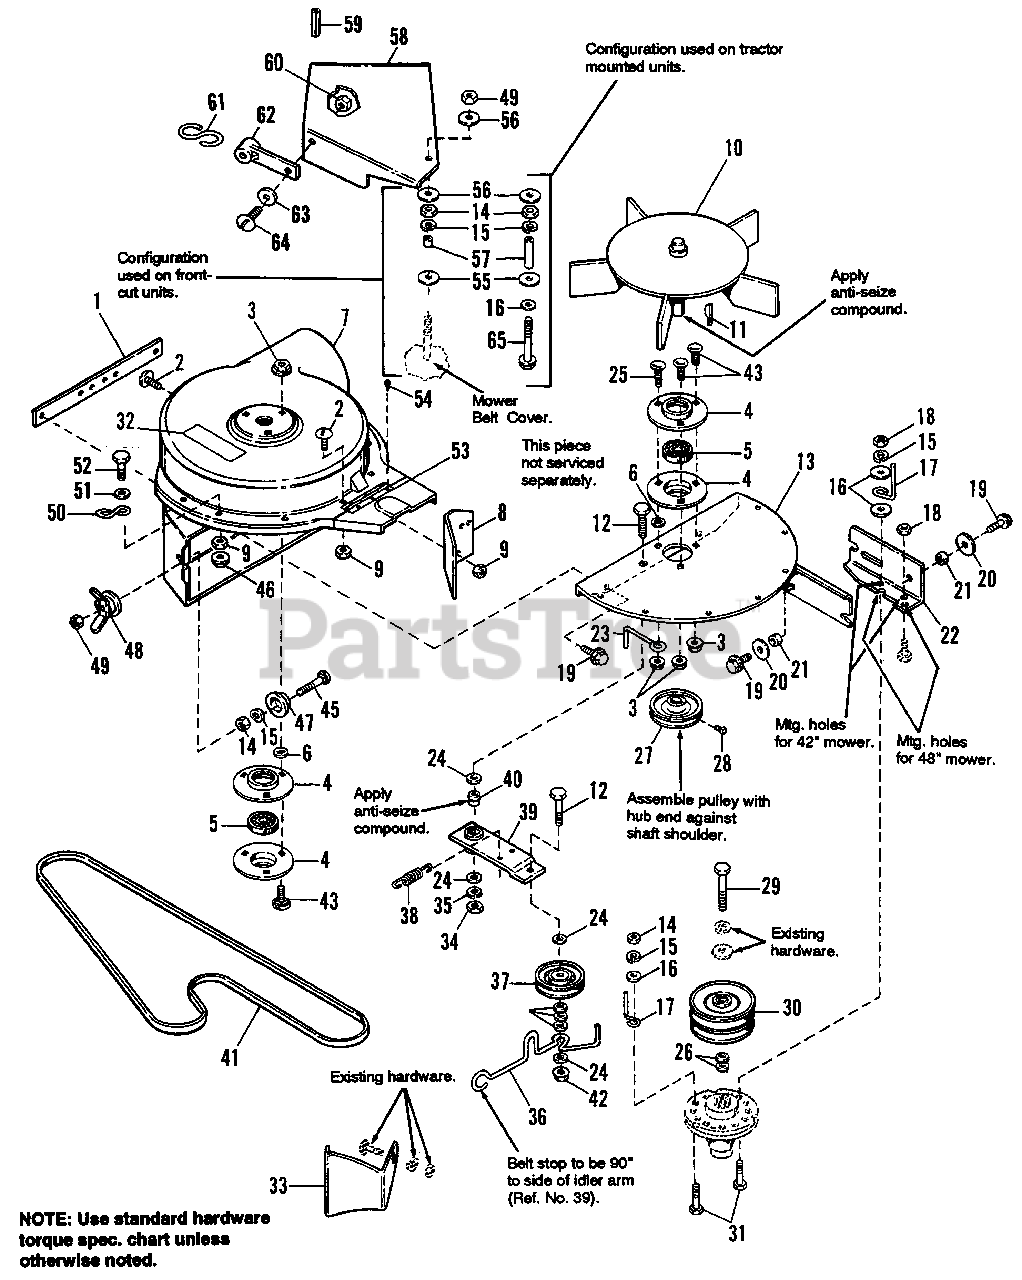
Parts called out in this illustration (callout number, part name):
1	STRIP, Reinforcement, Blower Housing
2	SCREW, Truss Hd., 1/4-20 x 5/8
3	NUT, Flange Lock, 5/16-18
4	BEARING, Retainer
6	PUSHNUT, 5/16
7	FAN HOUSING & HINGE ASSY. (Inc. Ref. Nos. 32, 53 & 54)
8	BAFFLE, Fan Housing
9	NUT, Hex, Nylon Lock, 1/4-20
10	FAN ASSY., 5 Blades
12	CAPSCREW, Hex, 3/8-16 x 1-3/4
13	PLATE ASSY.
14	NUT, Hex, Full 5/16-18
15	LOCKWASHER, 5/16
16	WASHER, Plain (Qty. 4 used on tractor mounted units)
18	NUT, Hex Jam Lock, 5/16-18
19	SCREW, Tapbte, 1/4-20 x 5/8
20	WASHER, 1/4
22	BRACKET, Arbor
24	WASHER, Plain, 13/32
25	CARRIAGE BOLT, 5/16-18 x 7/8
26	WASHER (As Required)
27	PULLEY, Driven
28	SETSCREW, Sq. Hd., 5/16-18 x 3/8
29	CAPSCREW, Hex, 7/16-14 x 2-1/4
30	PULLEY ASSY.
31	CAPSCREW, Hex, 5/16-18 x 1-1/2
32	DECAL, Danger, Blower
33	BAFFLE, Discharge
34	NUT, Hex, Full, 3/8-16
35	LOCKWASHER, 3/8
37	PULLEY, Idler
38	SPRING, Tension
39	IDLER ARM ASSY.
40	SPACER
41	BELT, Turbo
42	Nut, Hex, Flange Lock, 3/8-16
43	CARRIAGE BOLT, 5/16-18 x 3/4
44	PLATE, Flange, Blower Housing
45	CARRIAGE BOLT, 5/16-18 x 2 1/4
46	NUT, FLANGE Lock, 1/4-20
48	NUT ASSY., Wing
49	NUT Hex, Full, Lock, 5/16-18
51	WASHER, Plain, 9/32
52	CAPSCREW, Hex Hd. 1/4-20 x 1-1/4
55	WASHER, Special
56	WASHER, Plain
58	COVER ASSY., Pulley
60	NUT, Hex, Full Lock, #10-32
63	WASHER, Special
64	SCREW, Truss, #10-32 x 1/2
65	CAPSCREW, Hex 5/16-18 x 5-1/2 (used on tractor mounted units only)
